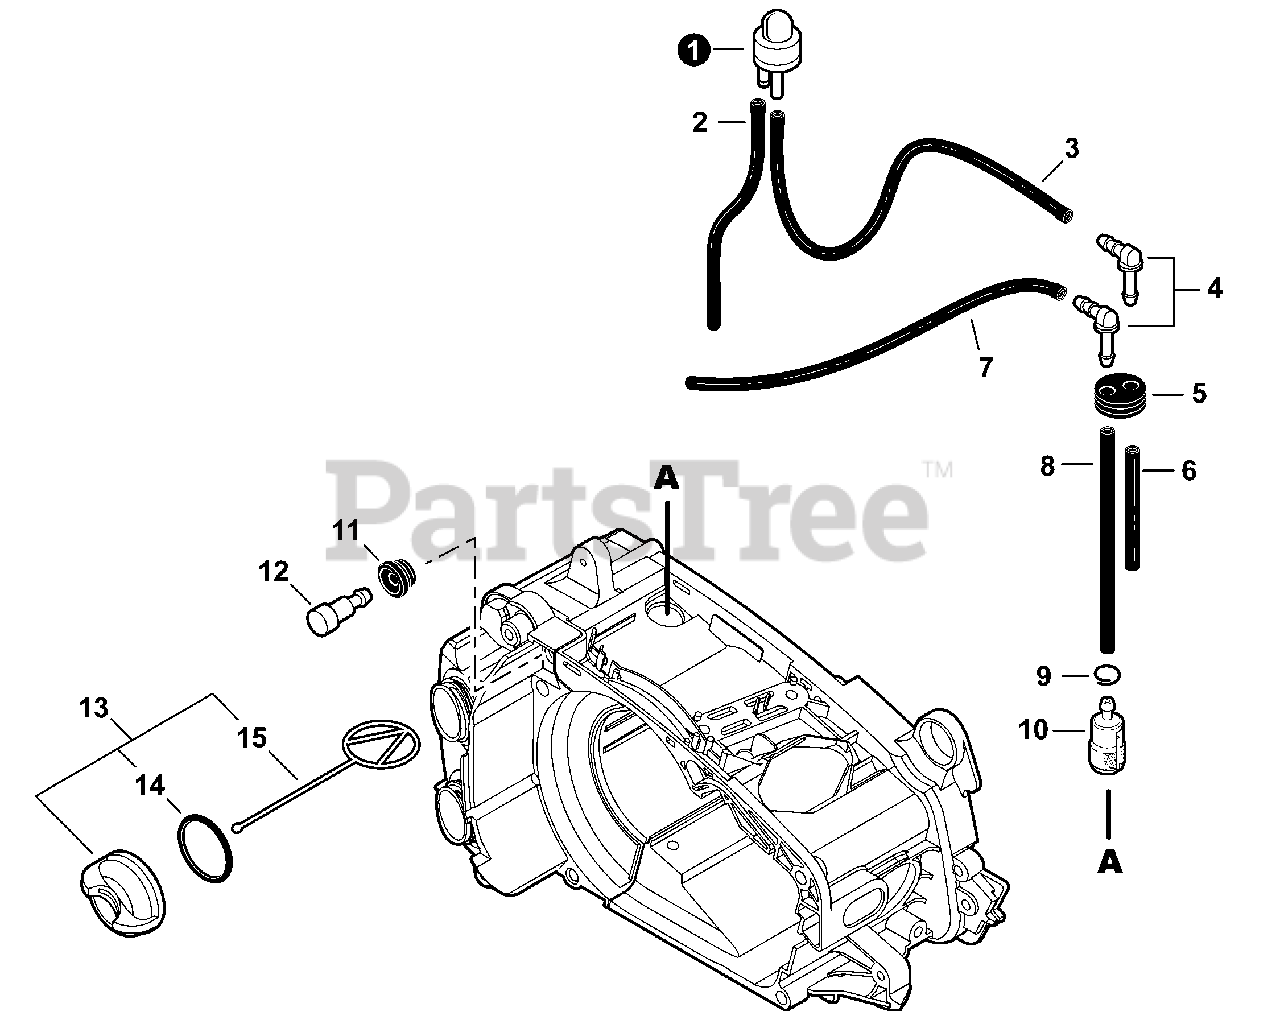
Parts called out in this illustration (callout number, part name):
1	BULB, PURGE
2	PIPE 2.4×5×180 - BLACK
3	PIPE 2.4×5×400 - BLACK
4	CONNECTOR, PIPE
5	GROMMET, FUEL
6	PIPE 2.4×5×15 - BLACK
7	PIPE 3×5×265 - BLACK
8	PIPE 3×5×140 - BLACK
9	CLIP Ø6
10	FILTER, FUEL
11	GROMMET, FUEL
12	VENT ASSY
13	CAP ASSY
14	O-RING 18
15	CONNECTOR, CAP L= 60 MM
